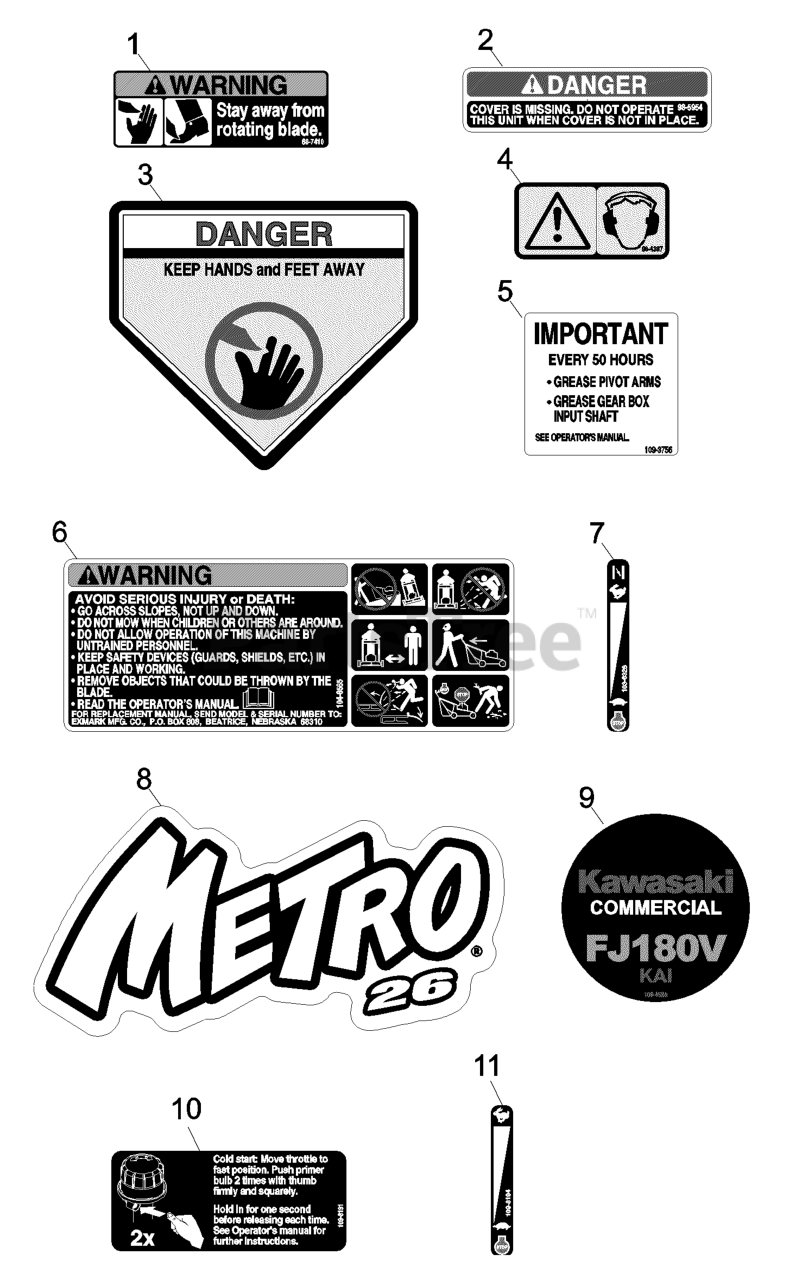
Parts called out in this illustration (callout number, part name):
1	DECAL-BLADE
2	DECAL-COVER, MISSING
3	DECAL-DANGER
4	DECAL-PROTECTION, EAR
5	DECAL,SERVICE M26
6	DECAL-WARNING
7	DECAL-THROTTLE / CHOKE
8	DECAL,METRO 26
10	DECAL, PRIMER
11	BOLT-HANDLE
